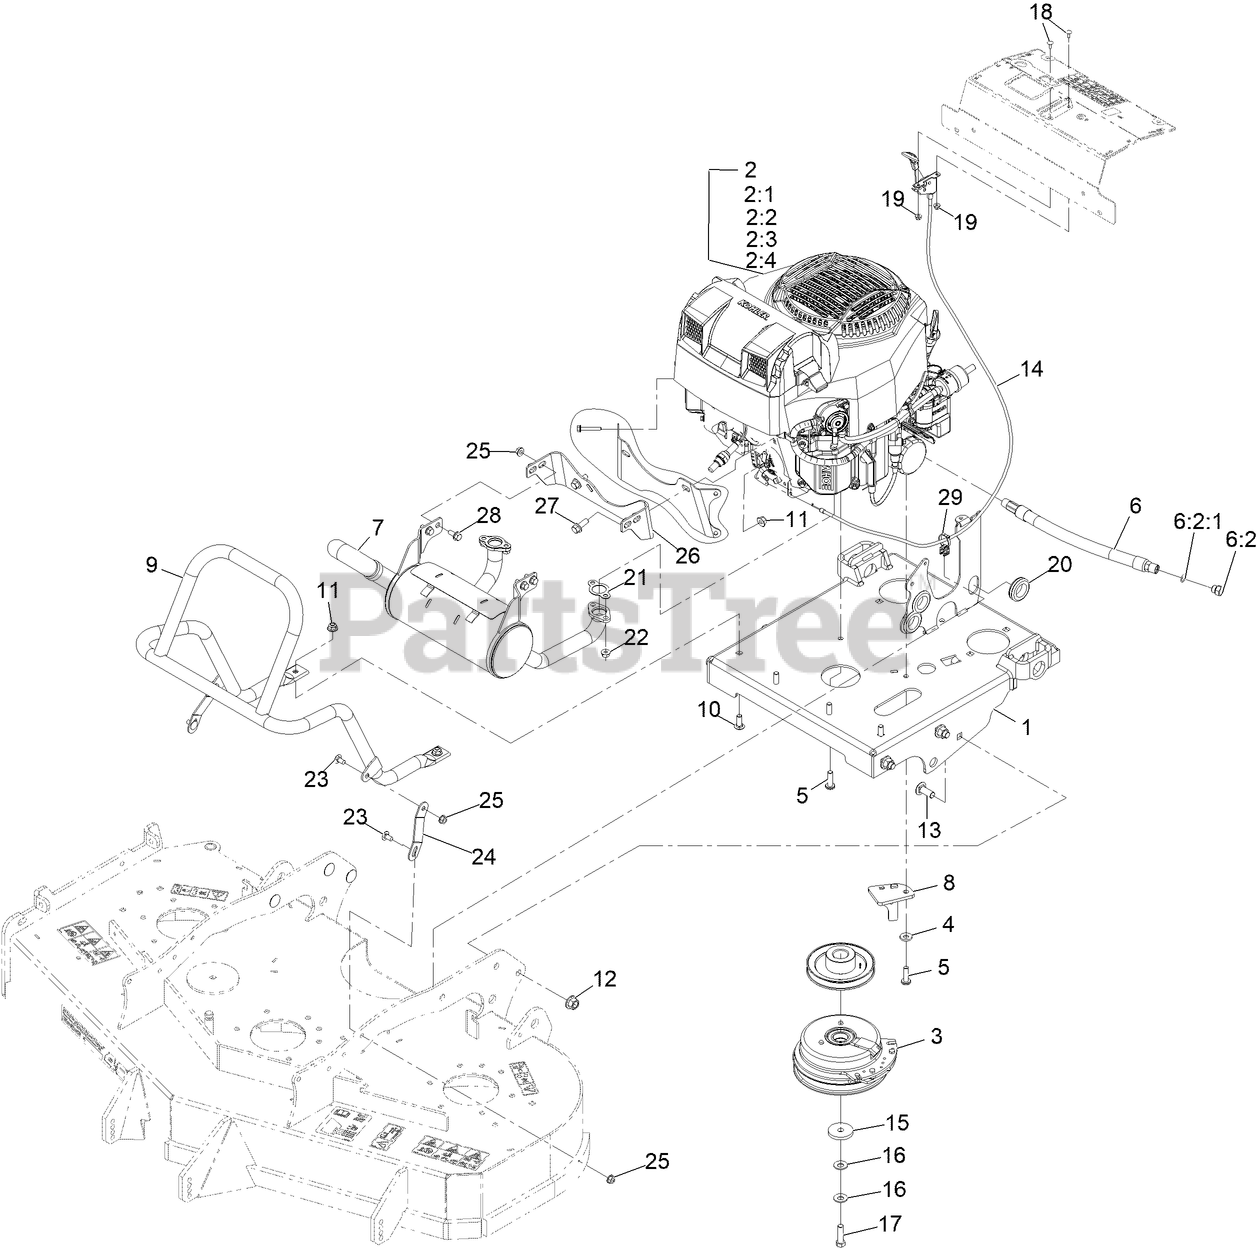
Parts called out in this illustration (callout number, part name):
1	ASM-ENGINE DECK
2:1	Element Pre-Cleaner
2:2	Kohler 16 083 01-S Engine Air Filter
2:3	Filter-Oil
2:4	Kohler 24 050 13-S Fuel Filter
4	WASHER-BELLEVILLE
5	Screw-PH-T45
6	OIL DRAIN HOSE ASM
6:2	PLUG-HH
6:2:1	O-RING
7	MUFFLER- KOHLER, EFI
8	ASM-CLUTCH ANCHOR
9	Tube-Guard Muffler
10	SCREW-CARR
11	NUT-HF, NI
12	Nut-Lock 1/2-13
13	SCREW-CARR, SHORT NECK
14	CONTROL,THROTTLE
15	WASHER-CLUTCH
16	WASHER-SPRING
17	SCREW-HH 7/16-20 X 1 1/2 W/LOCTITE
18	BOLT-CARR
20	GROMMET
21	GASKET-EXHAUST
22	NUT-FLANGE
23	SCREW-CARR
24	Strap, Muffler Guard
26	BRACKET-MUFFLER
27	SCREW-HHF 3/8-16 X 1
28	SCREW-HHF
29	Clip-Edge W/Tie, Perpendicular
